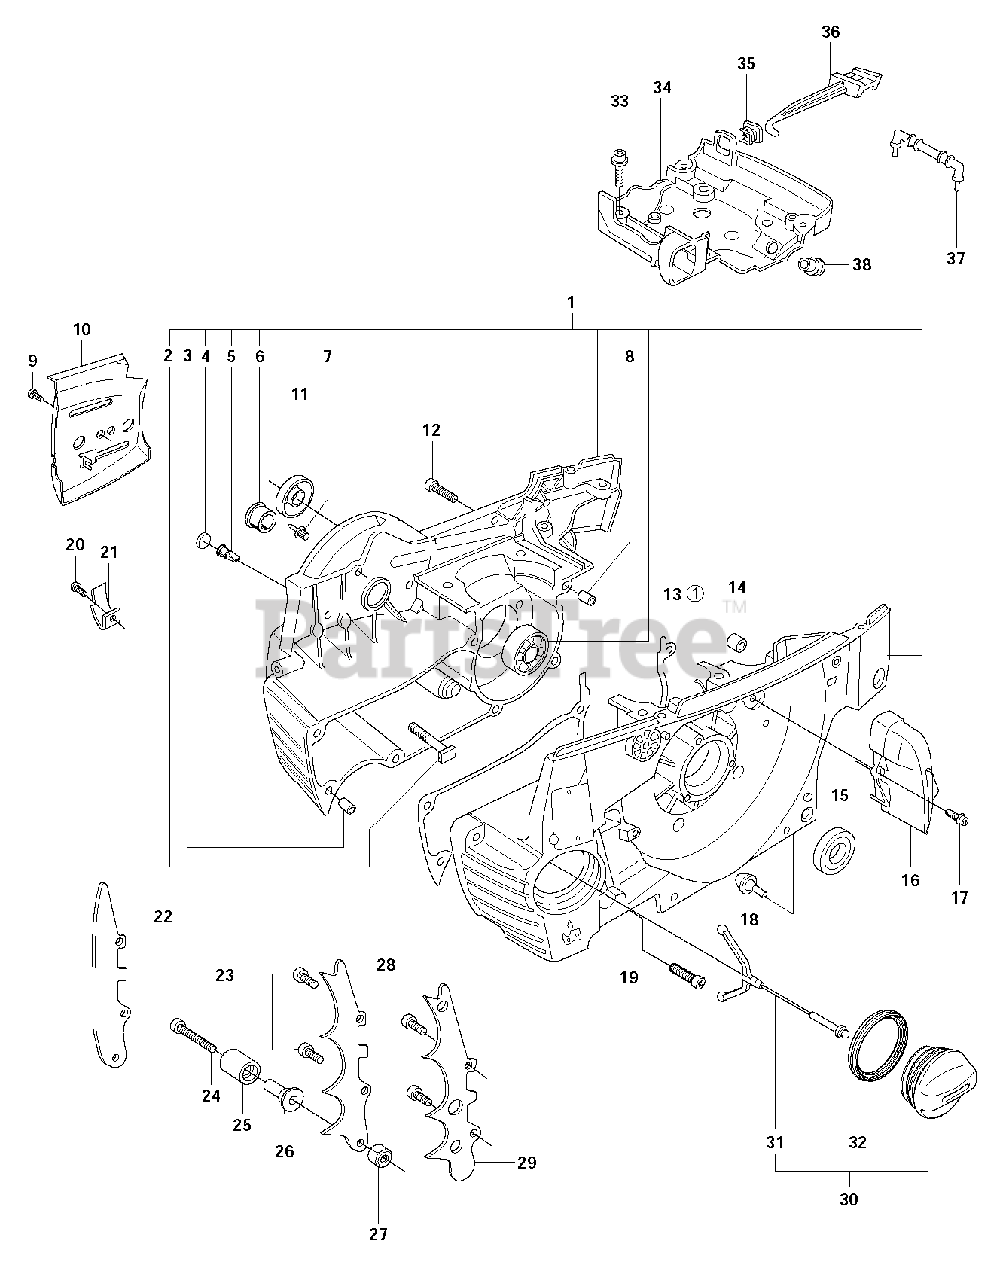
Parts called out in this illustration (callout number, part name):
1	CRANKCASE ASSY
2	BOLT
3	SLEEVE
4	VALVE-CHECK (DUCKBILL)
5	PLUG
6	BUSHING
7	PIN
8	SLEEVE
10	BAR PLATE
14	PROTECTOR
15	SEAL RING
20	SCREW MC6S 5X20
21	CHAIN CATCHER
28	FELLING DOG
29	FELLING DOG
30	TANK CAP
31	HOLDER
32	SEALING
34	BASE
36	CHOKE CONTROL
37	SPACER
